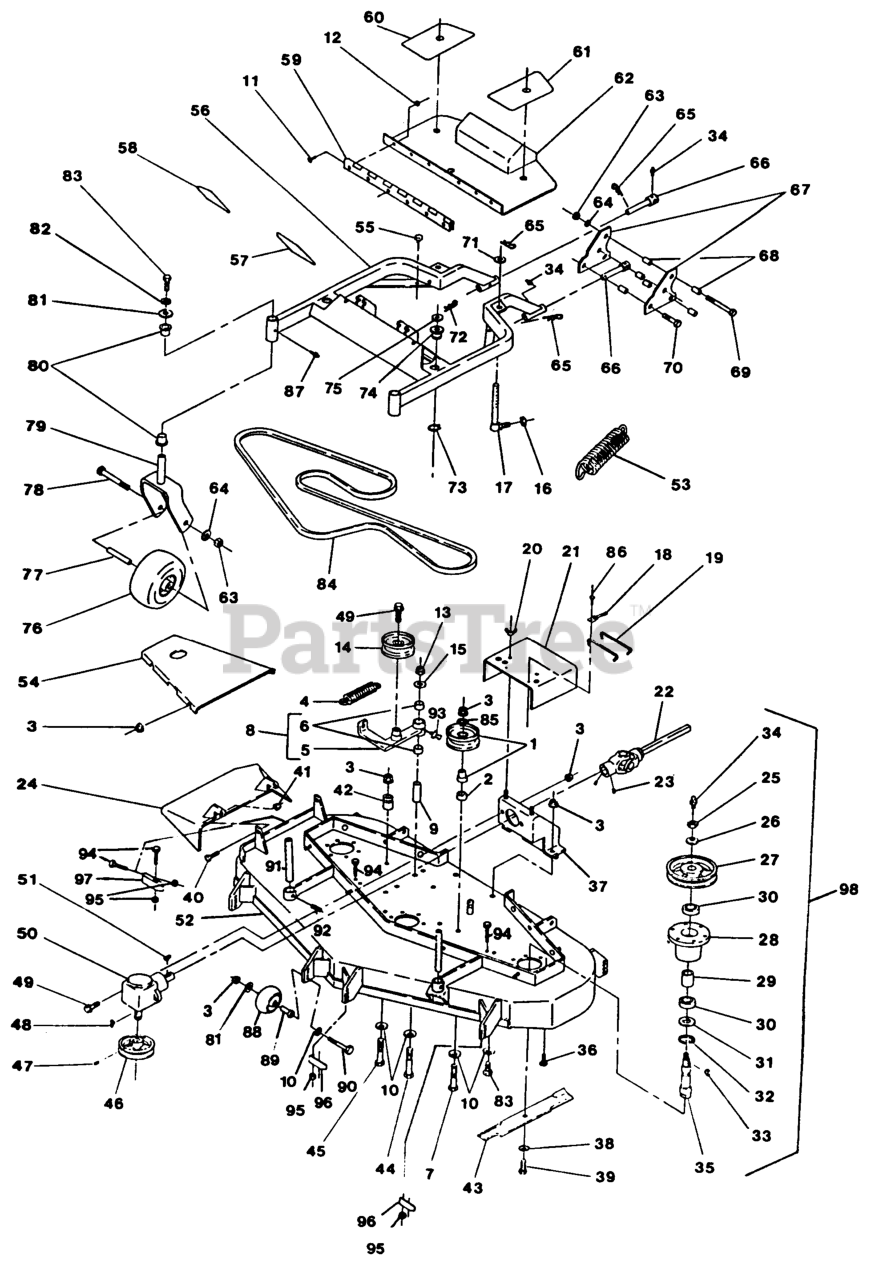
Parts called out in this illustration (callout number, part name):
1	KIT,48 RH IDLER/BUS
4	SPRING,EXTENSION
6	SLEEVE-BEARING
9	BUSHING
14	IDLER,PULLEY
18	CLIP-DECK, HOLD UP ROD
20	WINGNUT-NYLOCK
22	PTO SHAFT,SHAFT HALF PNT
24	WLD,CHUTE DISCHARGE
26	WASHER-SPRING
27	SHEAVE,BLADE DRIVE
29	SPACER,BEARING
31	SEAL,MECHANICAL DUST
32	RING,SNAP WLDS N5000-244
35	SPINDLE-OUTER BLADE
36	SCRW,TPTTE HH
37	WLD,GEARBOX SUPPORT
38	WASHER-SPRING
42	ANCHOR-SPRING PLTD
47	SCREW-SET
50	GEARBOX, PEERLESS
57	PAD,ANTI SKID UPPER LH
58	PAD,ANTI SKID UPPER RH
59	HINGE,FLOORPAN
60	PAD,ANTI SKID LOWER RH
65	PIN,HAIR COTTER
66	PIVOT - MOUNTING, W/ZERK
71	SPACER,REAR DK SUPP PLTD
74	BUSHING-DECK
75	SPACER-CASTER
80	BEARING-FLANGED
86	Pop Rivet, Steel 3/16 X .250
88	ROLLER-SCALP, ANTI
89	BUSHING-ROLLER
91	ROD,DECK SUPPORT
97	WLD,BAFFLE DISCHARGE
98	CH-52&60 OUTER CUTTR
